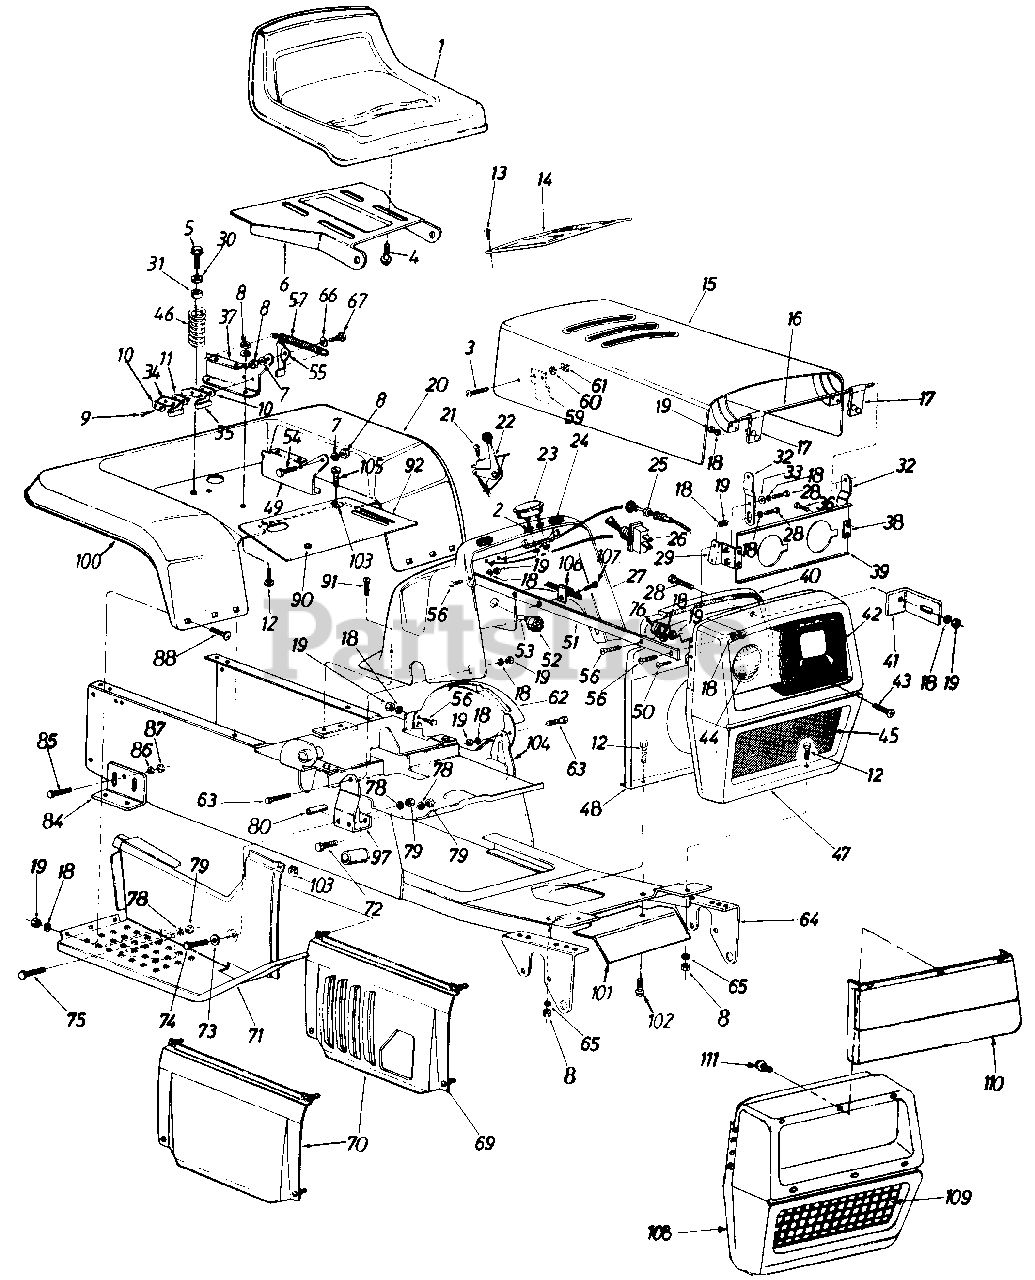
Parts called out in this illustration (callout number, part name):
1	Seat Ass'y. (Black)
2	L-Wash. .190" I.D.
3	Truss Hd. Mach. Scr. #10-24 x .38" Lg.
4	Hex Wash. Hd. Self-Tap Scr. 3/8-16 x .75" Lg.
5	Hex Wash. Hd. Tap Scr. 5/16-18 x .75" Lg.
7	L-Wash. 5/16" I.D.
8	Hex Nut 5/16-18 Thd.
9	Hex Wash. Hd. AB-Tap Scr. #8 x .5" Lg.
10	Insulator Plate
11	Insulator Boss Plate
12	Hex Bolt 5/16-18 x .75" Lg.
13	Self-Tap Oval Hd. Scr. 1/2" Lg.
14	Dash Panel Cover
17	Hood Hinge Ass'y.
18	L-Wash. 1/4" I.D.
19	Hex Nut 1/4-20 Thd.
20	Rear Fender
22	Throttle Control
23	Ammeter
24	Rubber Bumper
25	Choke Control
26	Light Switch
27	Dash Panel
28	Hex Bolt 1/4-20 x .62" Lg.
29	Hood Support Brkt. Ass'y. - R.H.
30	Fl-Wash. .344" I.D. x .875"
31	Busing
34	Safety Switch (Seat)
35	Safety Switch (Seat)
36	Hex Bolt 1/4-20 x .38" Lg.
38	Hood Support Brkt. Ass'y. - L.H.
41	Heat Shield Brkt.
42	Head Lamp Bezel
43	Truss Mach. Scr. #10-24 x .50" Lg.
44	Head Lamp
46	Compression Spring 4.5" Lg.
50	Truss Mach. Scr. 1/4-20 x .75" Lg.
51	Grille Strap
52	Ignition Switch
53	Ignition Key
54	Shld. Bolt. 437" Dia. x .162"
55	Seat Lift Bracket
56	Hex Bolt 1/4-20 x .75" Lg.
57	Extension Spring 5.31" Lg.
59	Hood Spring
60	L-Wash. #10
61	Hex Nut #10-24 Thd.
62	Speed Control Guide
63	Truss Mach. Scr. 1/4-20 x .75" Lg.
66	Spr. Wash. .445" I.D. x .75"
67	Shld. Bolt .437" Dia. x .268"
69	Truss Mach. Scr. #10-24 x .5" Lg.
73	Fl-Wash. .385" I.D. x .62" O.D.
74	Hex Bolt 3/8-16 x 3.00" Lg.
75	Hex Bolt 3/8-16 x 1.00" Lg. Grade 5
76	Snap Bushing
78	L-Wash. 3/8" I.D.
79	Hex Nut 3/8-16 Thd.
80	Spacer .375" I.D. x .62" O.D. x 2.00" Lg.
84	Transaxle Support Brkt.
85	Rd. Hd. Rib Neck Scr. 3/8-24
86	L-Wash. 3/8" I.D.
87	Hex Nut 3/8-24 Thd. (Gr. 5)
88	Carr. Bolt 1/4-20 x .50" Lg.
90	Snap Bushing
91	Hex Wash. Hd. Tap Scr. 1/4-20 x .5" Lg.
103	Speed Nut #10-24 Thd.
104	Dash Panel Mtg. Brkt. - L.H.
105	Truss Mach. Scr. #10-24 x .5" Lg.
106	Clamp
107	Self-Tap Scr. 5/16 x .5" Lg.
110	Headlight Bezel
111	Hex Wash. Hd. Scr. #8 x .5" Lg.
